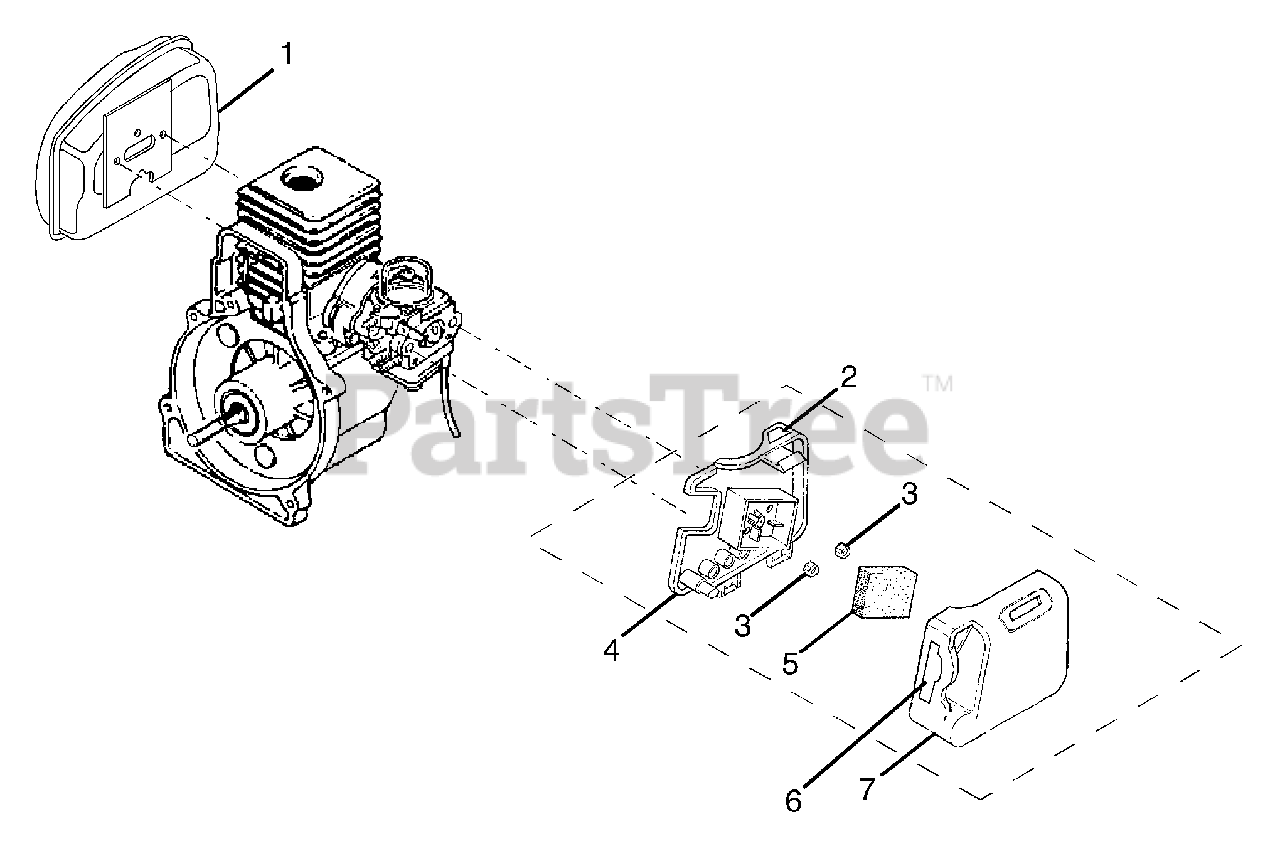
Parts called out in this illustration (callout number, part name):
1	MUFFLER ASSEMBLY
2	PRIMER DECAL
3	LOCK NUT (10-24)
4	BOX AIR FILTER (CONEHEAD)
5	AIR FILTER
6	CHOKE DECAL
7	AIR BOX COVER
